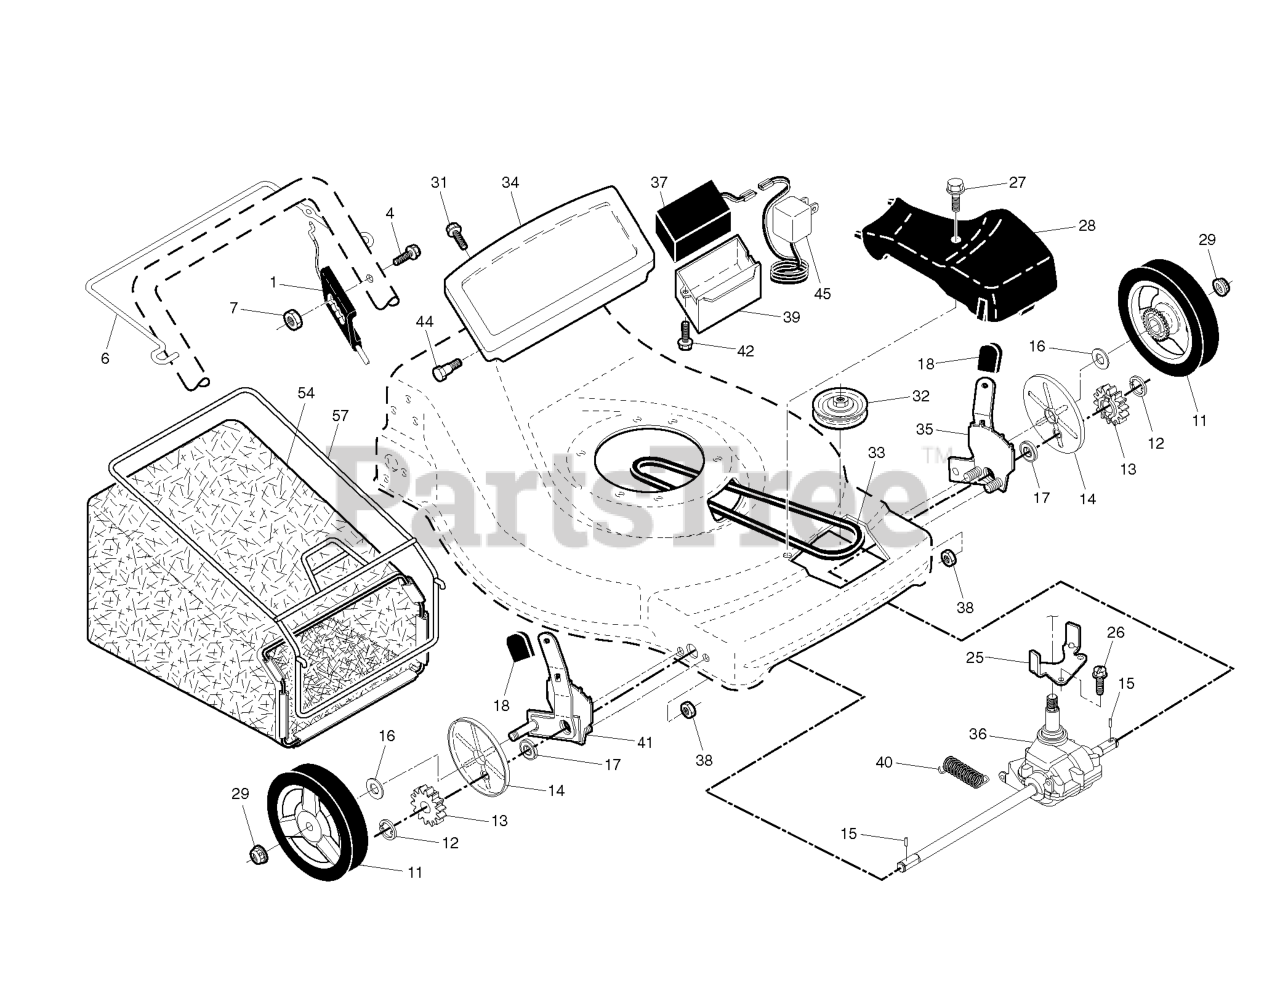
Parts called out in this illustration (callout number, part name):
1	CABLE.DR.VS.BOLT-ON.AUTO.FGD L
6	BAIL.CONT.DR.S/S.ROUND.ORG
7	NUT.HEX.FLANGE.1/4
11	WHEEL.8X1.75.H3SPK.RAD3.GY.BU3
12	E-RING 7/16 RE
13	PINION.14.TEETH.FGD
14	COVER.DUST.WHEEL
15	PAWL, DRIVE
16	WASHER FLUT
17	BEARING.ASM.
18	SELECTOR KNOB
25	BRACKET.BELT.GUIDE.22+FGD.BZP
26	SCREW
26	Screw
27	SCREW, HEX HD TAPPING #10-24 1
28	COVER.DR.ASM.194407X498.CE
28	RP DRIVE COVER
29	NUT.HEX.FLANGE.3/8-16.LO(3 2)
31	SCREW
31	SCREW.PAN.HEAD.#10
32	RP PULLEY.DRIVE.EZ/VAR.SCREWON
33	BELT.DRIVE.FG
34	PANEL.TRIM.21.FWGD.ES
35	KIT ADJUSTER ASM.438151.
36	TRANSMISSION.22.VS.FWGD
37	BATTERY WITH AMP CONECTOR AGM
38	LOCKNUT.NYLOC.1/4-20
39	BOX.BATTERY.TRIM
41	KIT ADJUSTER ASM.438148
42	SCREW.HWH.13-16X.50
44	SCREW.SHOULDER.HH.10X.281X.6
45	RP CHARGER.12V.0.1A
54	GBAG.83230247T.SIL.HUSQ.BLU
57	FRAME.GBAG.22.EZ.EMPTY.SC
